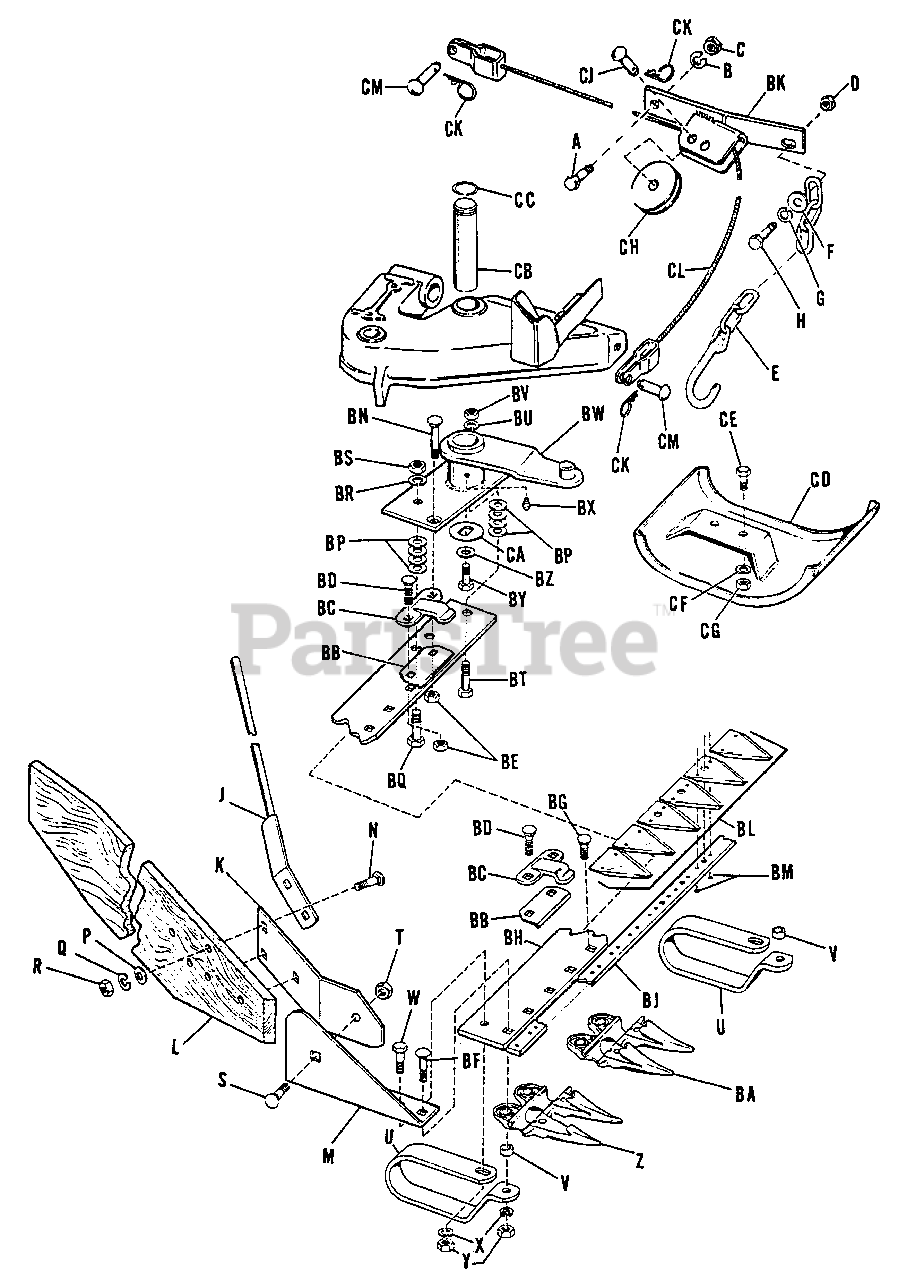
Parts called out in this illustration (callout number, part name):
A	Capscrew, Hex Hd, 5/16"-18" NC x 1" lg.
B	Washer Lock 5/16" (For "725" Only-Rear)
C	Hex Nut Full 5/16"-18" NC (For "725" Only-Rear)
D	5/16"-18" NC x 1-1/4" lg. (Landlord Front)
E	Chain Assembly, Transport
F	Washer, Plain
G	Washer, Lock, 3/8"
H	Capscrew, Hex Hd., 3/8"-16 NC x 1-1/4" lg. (For "725" Front)
J	Divider Rod Assembly
K	Support, Divider Board
L	Board, Divider
N	Bolt, Carriage, 3/8"-16 NC x 1-1/2" lg.
P	Washer, Plain, 3/8"
Q	Lockwasher, 3/8"
R	Nut, Hex, Full, 3/8"-16 NC
S	Bolt, Carriage, 3/8"-16 NC x 1" lg.
T	Nut, Hex, Full, Elastic Stop Nut, 3/8"-16 NC
W	Capscrew, Hex Hd., 3/8"-16 NC x 1-1/4" lg.
X	Lockwasher, 3/8"
Y	Nut, Hex, Full, 3/8"-16 NC
Z	Guard, Right End
BA	Guard Twin
BB	Plate, Wear
BC	Clip, Sickle
BD	Bolt, Carriage, 3/8"-16 NC x 1-1/4" lg.
BE	Nut, Hex, Full, 3/8"-16 NC
BF	Bolt, Carriage, 3/8"-16 NC x 1-3/4" lg.
BG	Bolt, Carriage, 3/8"-16 NC x 1" lg.
BH	Bar, Cutter
BJ	Sickle Bar, Complete
BK	Pulley Mounting Assy.
BL	Complete Set of Sections
BM	Rivet, Round Head, #6 x 1/2" lg.
BN	Bolt, Plow, 3/89-16 NC x 1-3/4" lg.
BP	Washer, Plain, 3/8"
BQ	Capscrew, Hex Hd., 3/8"-16 NC x 1-1/2" lg.
BR	Lockwasher, 3/8"
BS	Nut, Hex Full, 3/8"-16 NC
BT	Capscrew, Hex Hd, 7/16"-14 NC x 1-1/2" lg.
BU	Washer, Lock, 7/16"
BV	Nut, Hex, Full, 7/16"-14 NC
BW	Lever Assembly, Cutter Bar
BX	Fitting, Grease
BY	Capscrew, Hex Hd., 3/8"-16 NC x 1" lg.
BZ	Washer, Plain, 3/8"
CB	Cutter Bar Shaft
CC	Ring, Retaining
CD	Shoe Assembly
CE	Capscrew, Hex Hd., 3/8"-16 NC x 1" lg.
CF	Lockwasher, 3/8"
CG	Nut, Hex, Full, 3/8"-16 NC
CK	Spring Clip
CL	Cable Assy.
